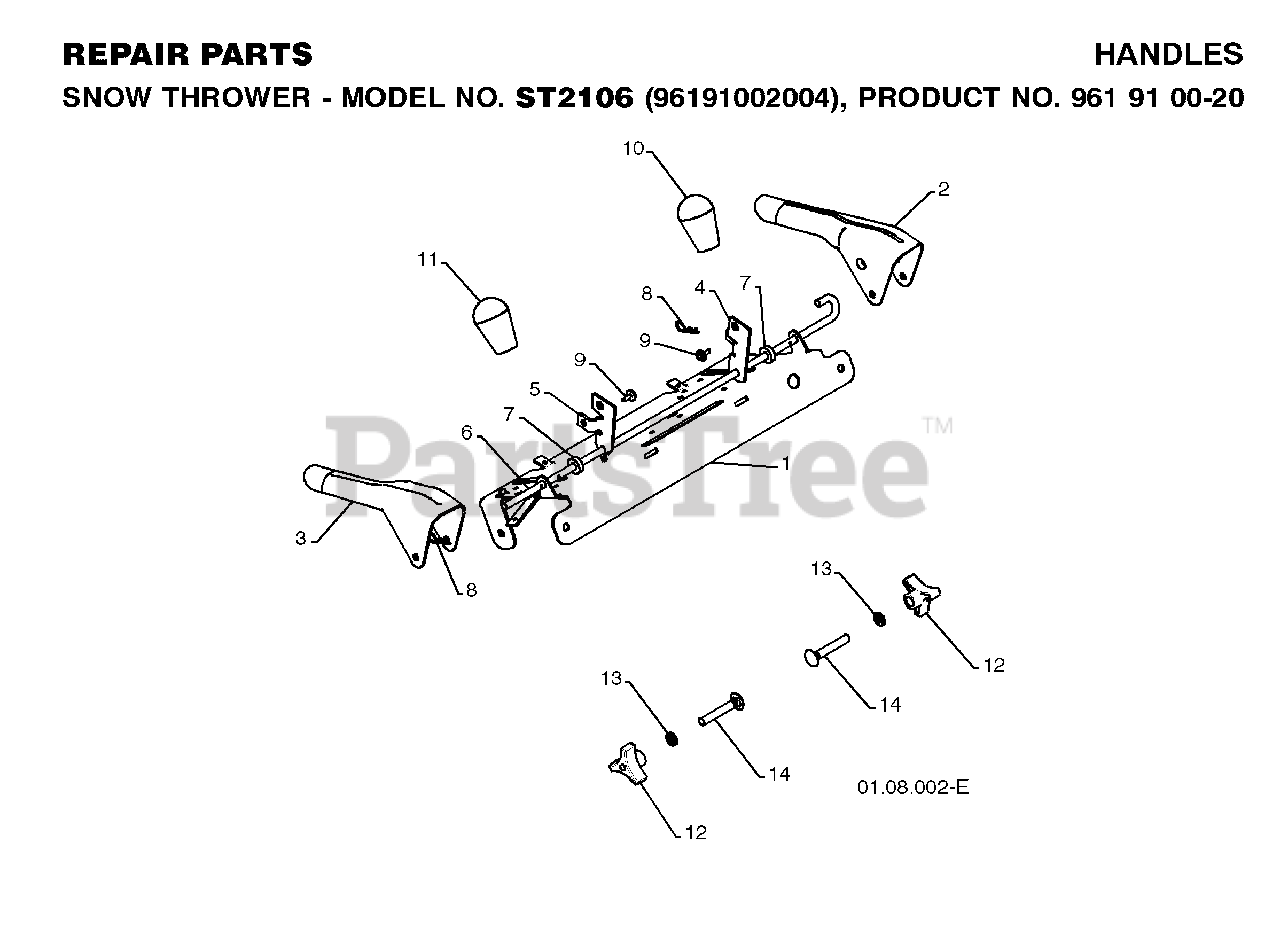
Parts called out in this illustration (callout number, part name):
1	CONTROL PANEL
2	LEVER.CONTROL.LH.PNT
4	TRACTION ROD ARM
5	ARM.IMPELLER.ROD.YZ
6	BAIL.CONTROL.INTERLOCK
7	SPACER.CONTROL.LEVER
8	SPRING RETAINER
10	KNOB LEVER, BLACK
11	RED KNOB SHIFTER
12	KNOB.HANDLE.3/8.TRI-POINT.BLAC
14	BOLT 3/8-16 X 2-1/4
